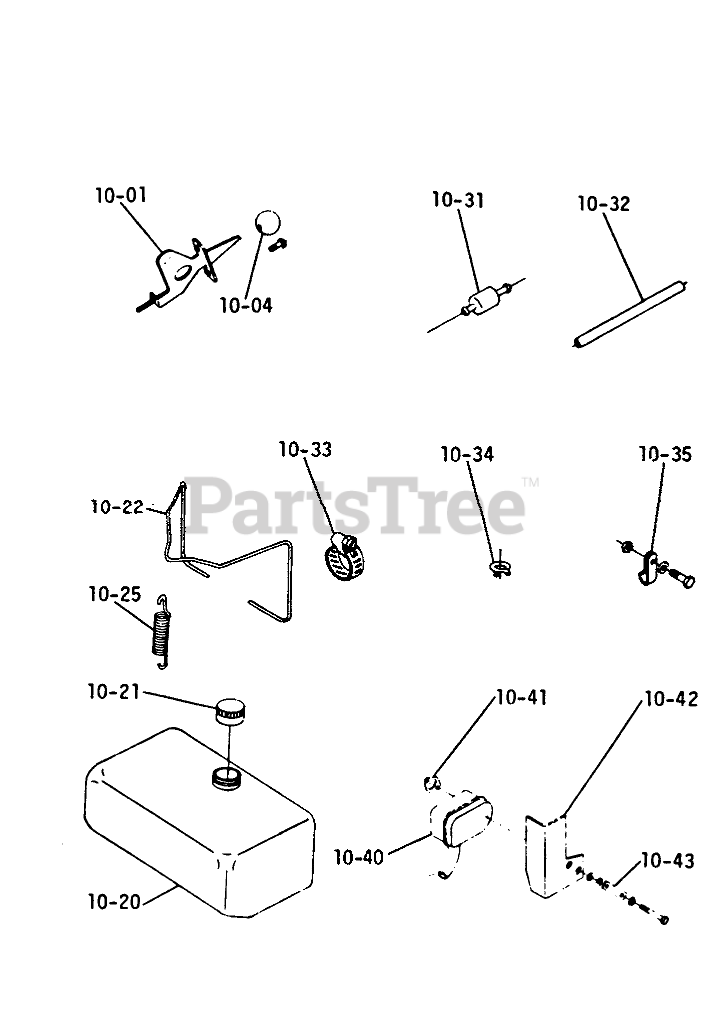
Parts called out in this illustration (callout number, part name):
10-01	Pin Oval Head
10-04	Knob-Control
10-20	Fuel Tank
10-21	Cap
10-22	Hold Down Wire
10-25	CLUTCH SPRING
10-31	Filter
10-32	Hose
10-33	CLAMP
10-34	Clamp
10-40	Muffler
10-41	Gasket-Exhaust
10-42	Shield-Heat
10-43	Bar-Support
